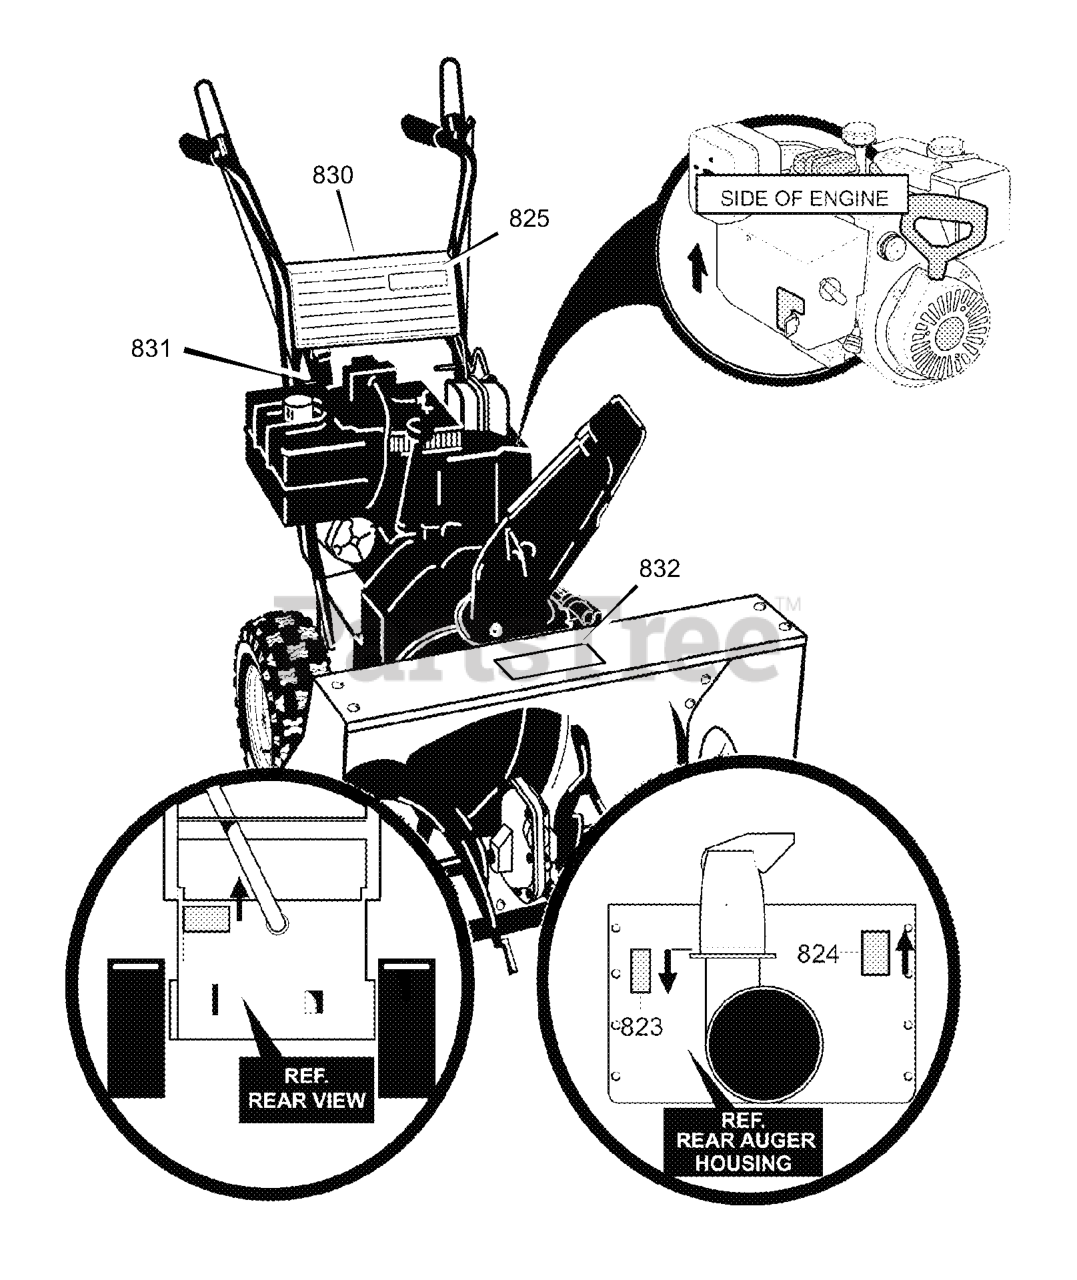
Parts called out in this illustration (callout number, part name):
823	DECAL, DANGER CHUTE HAND
824	DECAL, DANGER FOOT
825	DECAL, MURRAY SELECT
830	DECAL, TRACTION AUGER DRIVE
831	DECAL, GEAR SELECTOR
832	DECAL, 8/24
